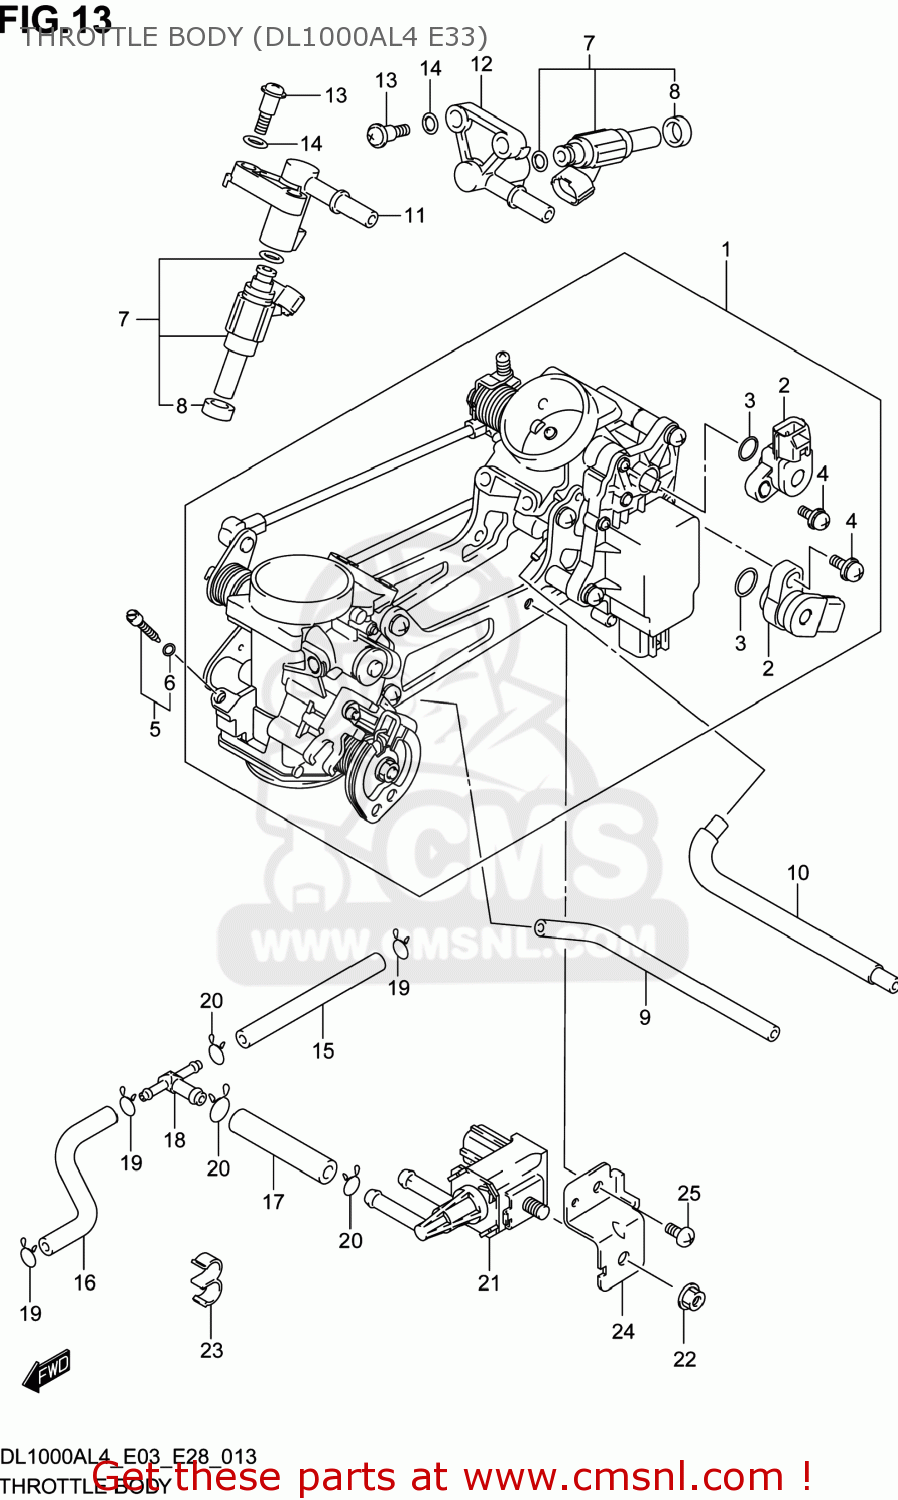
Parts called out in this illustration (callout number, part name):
1	BODY ASSY,THROTTLE
2	SENSOR
3	O RING
4	SCREW
5	ADJUSTER,BAS
6	O RING
7	INJECTOR ASSY
8	SEAL
9	HOSE
10	HOSE
11	DELIVERY PIPE
12	DELIVERY PIPE
13	SCREW
14	PACKING (NAS)
15	HOSE
16	HOSE
17	HOSE
18	NIPPLE
19	CLIP
20	CLIP
21	VALVE,CANISTER PURGE
22	NUT
23	CLIP
24	BRACKET
25	SCREW
